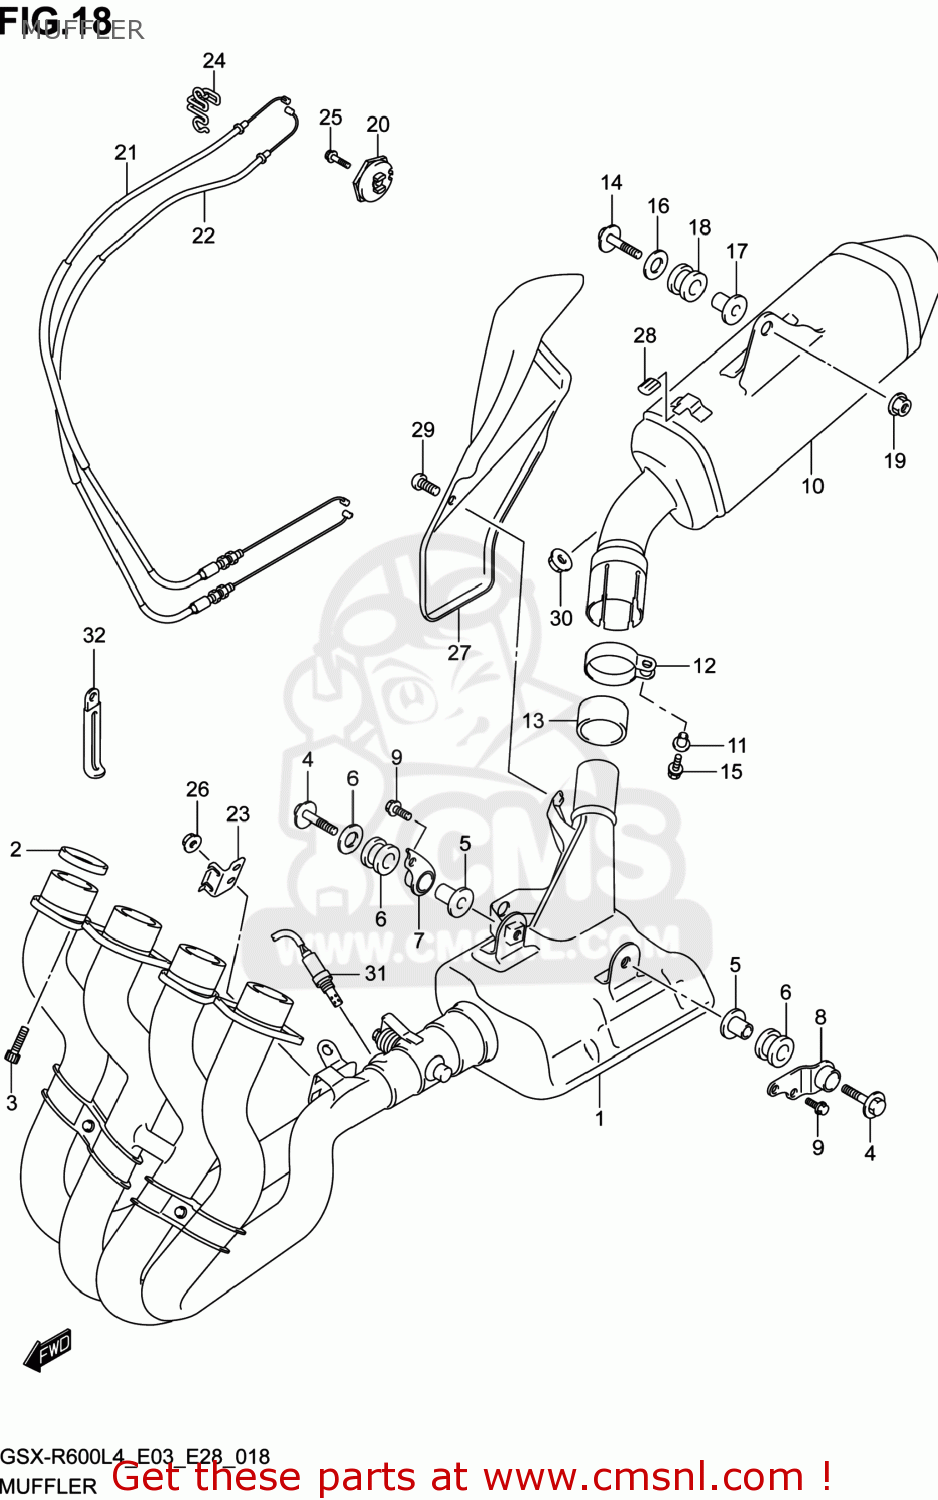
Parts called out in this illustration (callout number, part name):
1	EXHAUST
2	GASKET,EXHAUST PIPE
3	BOLT(8X25)
4	BOLT(8X45)
5	SPACER(8.6X12X24.2)
6	CUSHION
7	BRACKET,CHAMBER SPRT,R
8	BRACKET,CHAMBER SPRT,L
9	BOLT
10	BODY,MUFFLER
11	SPACER,MUF CLAMP
12	CLAMP,MUFFLER CONNECTOR
13	CONNECTOR,MUFFLER
14	BOLT(8X45)
15	BOLT(8X40)
16	WASHER(8.5X28X1.5)
17	SPACER(8.6X12X24.2)
18	CUSHION
19	NUT
20	PULLEY,CONTROLLER
21	CABLE,EXHAUST VALVE NO.1
22	CABLE,EXHAUST VALVE NO.2
23	BRACKET,EXHAUST VALVE CABLE
24	GUIDE,EXHAUST VALVE CABLE
25	BOLT
26	NUT
27	COVER,MUFFLER FR
28	GROMMET
29	SCREW(6X10)
30	CUSHION
31	SENSOR,OXYGEN
32	CLAMP(L:45)
